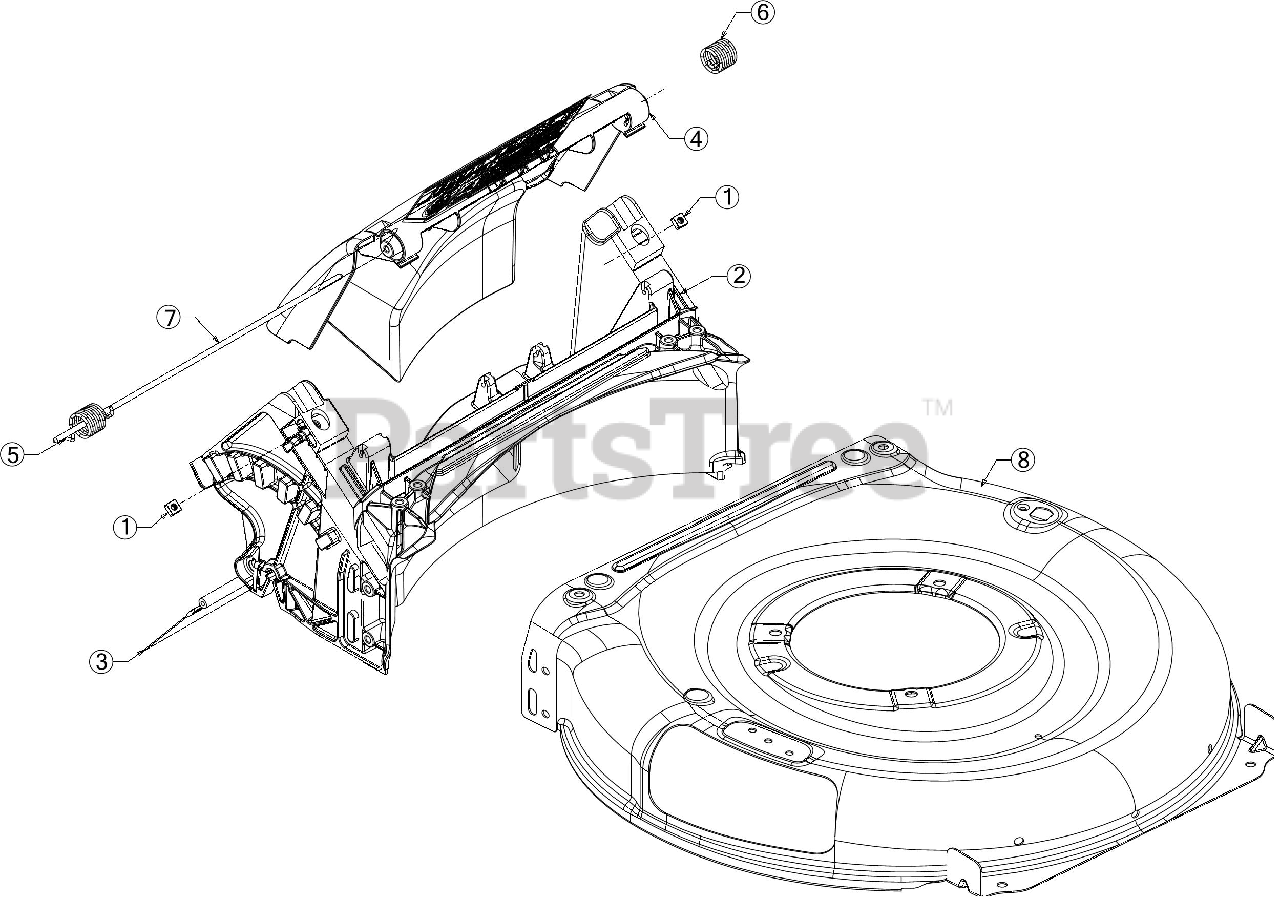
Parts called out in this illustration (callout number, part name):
1	SQUARE NUT 1/4-20
2	DOOR ASSEMBLY
3	TRAILSHIELD
5	TORSION SPRING (RH)
6	TORSION SPRING (LH)
7	REAR DOOR PIVOT ROD
8	21" DECK (3N1)
